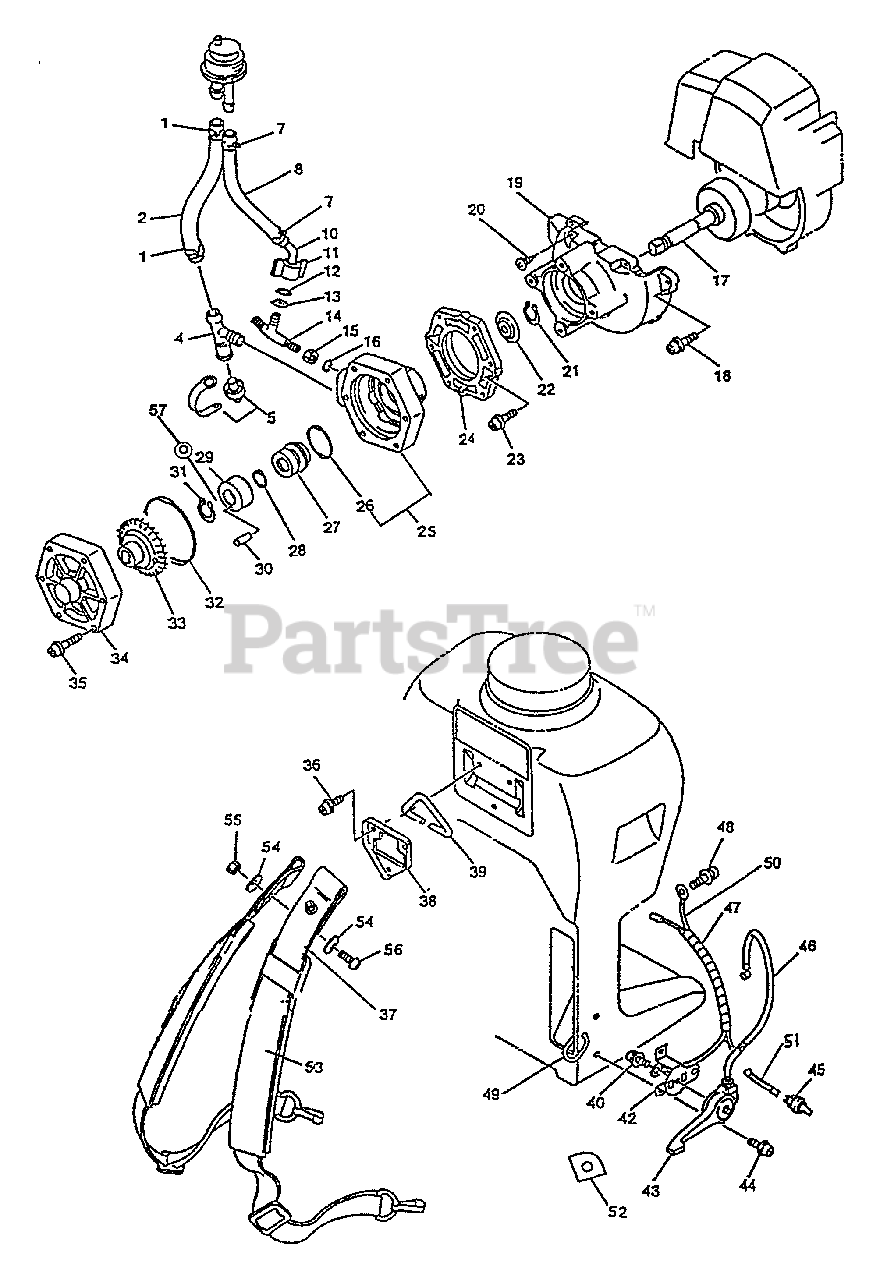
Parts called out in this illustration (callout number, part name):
4	FITTING, GREASE
5	DRAIN PLUG KIT
10	JOINT, BYPASS
11	NUT, WING
12	GASKET, BYPASS NOZZLE
14	NIPPLE, OUTLET PUMP
16	O-RING 10
17	DRUM, CLUTCH
18	SCREW 4×16
19	CASE, FAN
20	SCREW 4×16
21	RING, RETAINING - 12
23	SCREW 6×16
24	BRACKET, PUMP
25	CASE, PUMP
29	SEAL
31	E-RING 12
32	O-RING
33	IMPELLER
34	LID, PUMP
35	SCREW 5×40
36	SCREW 6×10
37	STRAP, BACKPACK
38	BRACKET, HANGER
40	SCREW 5×10
42	BRACKET, THROTTLE
43	LEVER, CONTROL
44	SCREW 5×16
45	SWITCH, ON-OFF
46	CABLE, THROTTLE
47	WRAP, SPIRAL
48	SCREW 5×10
49	RING, HARNESS
50	LEAD - GROUND
51	LEAD - GROUND
52	LABEL, ON-OFF
53	PAD, STRAP
54	WASHER 5.2×22×2.0
55	NUT, LOCK M5
56	SCREW 5×14
